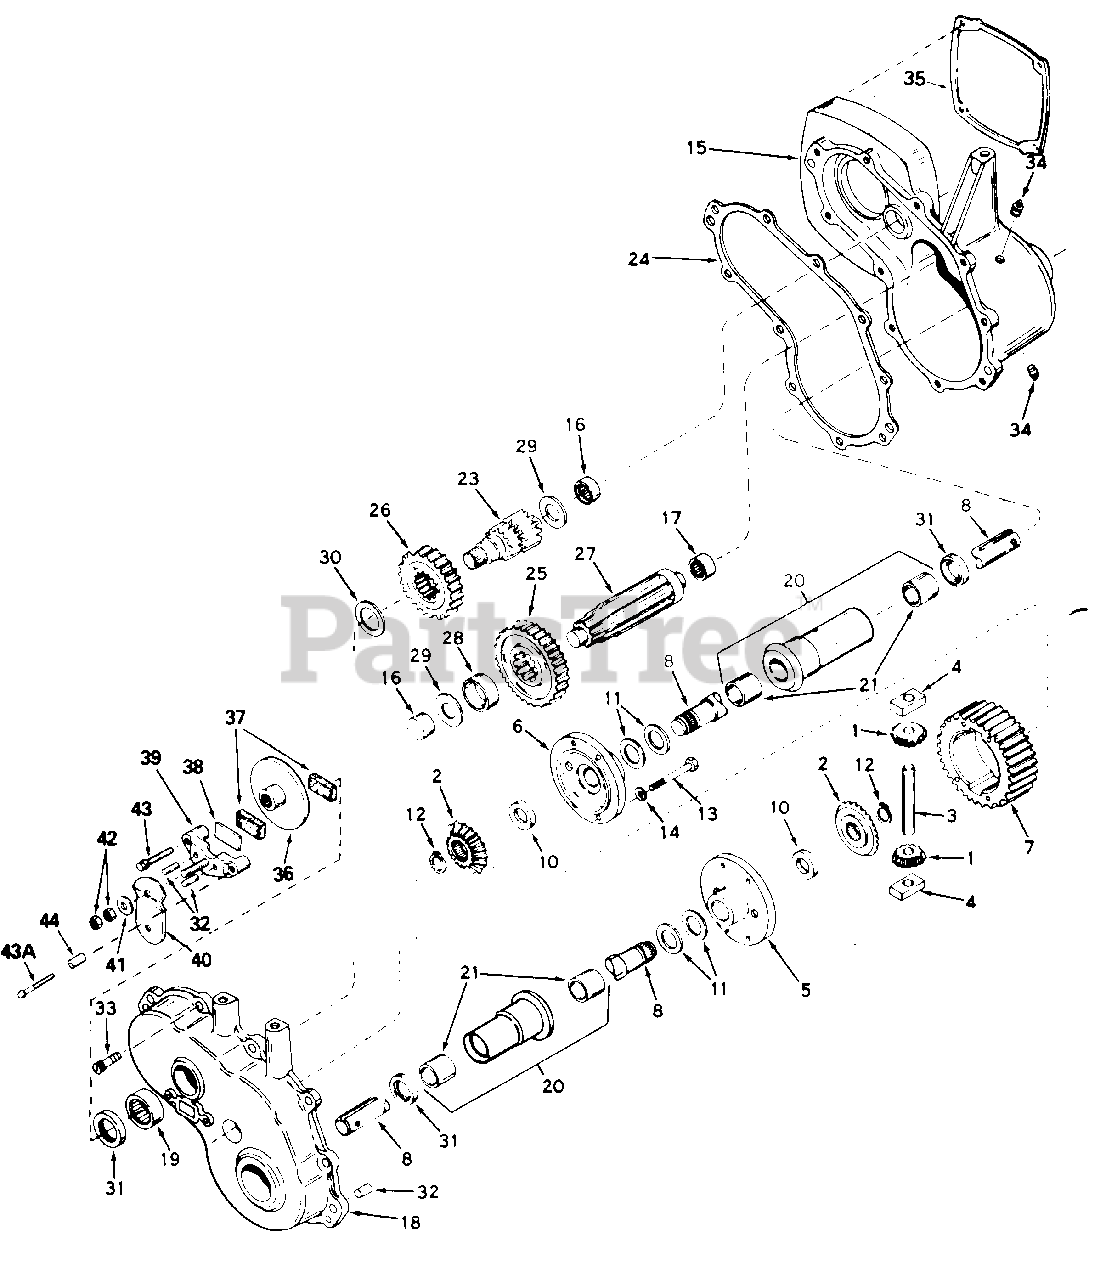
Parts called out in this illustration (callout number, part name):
1	Pinion, Bevel
2	Gear, Bevel
3	Pin, Drive
4	Block, Drive
5	Carrier, Differential
6	Carrier, Differential
7	Gear, Ring
8	Axle (16-1/64" Long)
10	Washer
11	Washer, Thrust
12	Ring, Snap
13	Screw, Hex Hd. 1/4-20 x 21/4
14	Lock Washer 1/4"
15	Case Ass'y.
16	Bearing, Needle
17	Bearing, Needle
18	Cover Ass'y.
19	Bearing, Needle
20	Housing Ass'y., Axle
21	Bushing
23	Shaft, Brake
24	Gasket, Case to Cover
25	Gear, Output
26	Gear, Idler
27	Shaft, Output
28	Spacer
29	Washer
30	Washer
31	Seal, Oil
32	Pin, Dowel
33	Screw, Hex Hd., Self-Tapping, 1/4-20 x 1
34	Plug, Pipe
35	Gasket
36	Disc, Brake
37	Pad, Brake
38	Plate, Brake Pad
39	Holder, Brake Pad
40	Lever, Brake
41	Washer, Flat
42	Lock Nut 5/16-24
43	Screw, Hex Hd., Self-Tapping, 1/4-20 x 1 1/4
43A	Screw, Hex Hd., Self-Tapping, 1/4-20 x 2 1/4
44	Spacer
